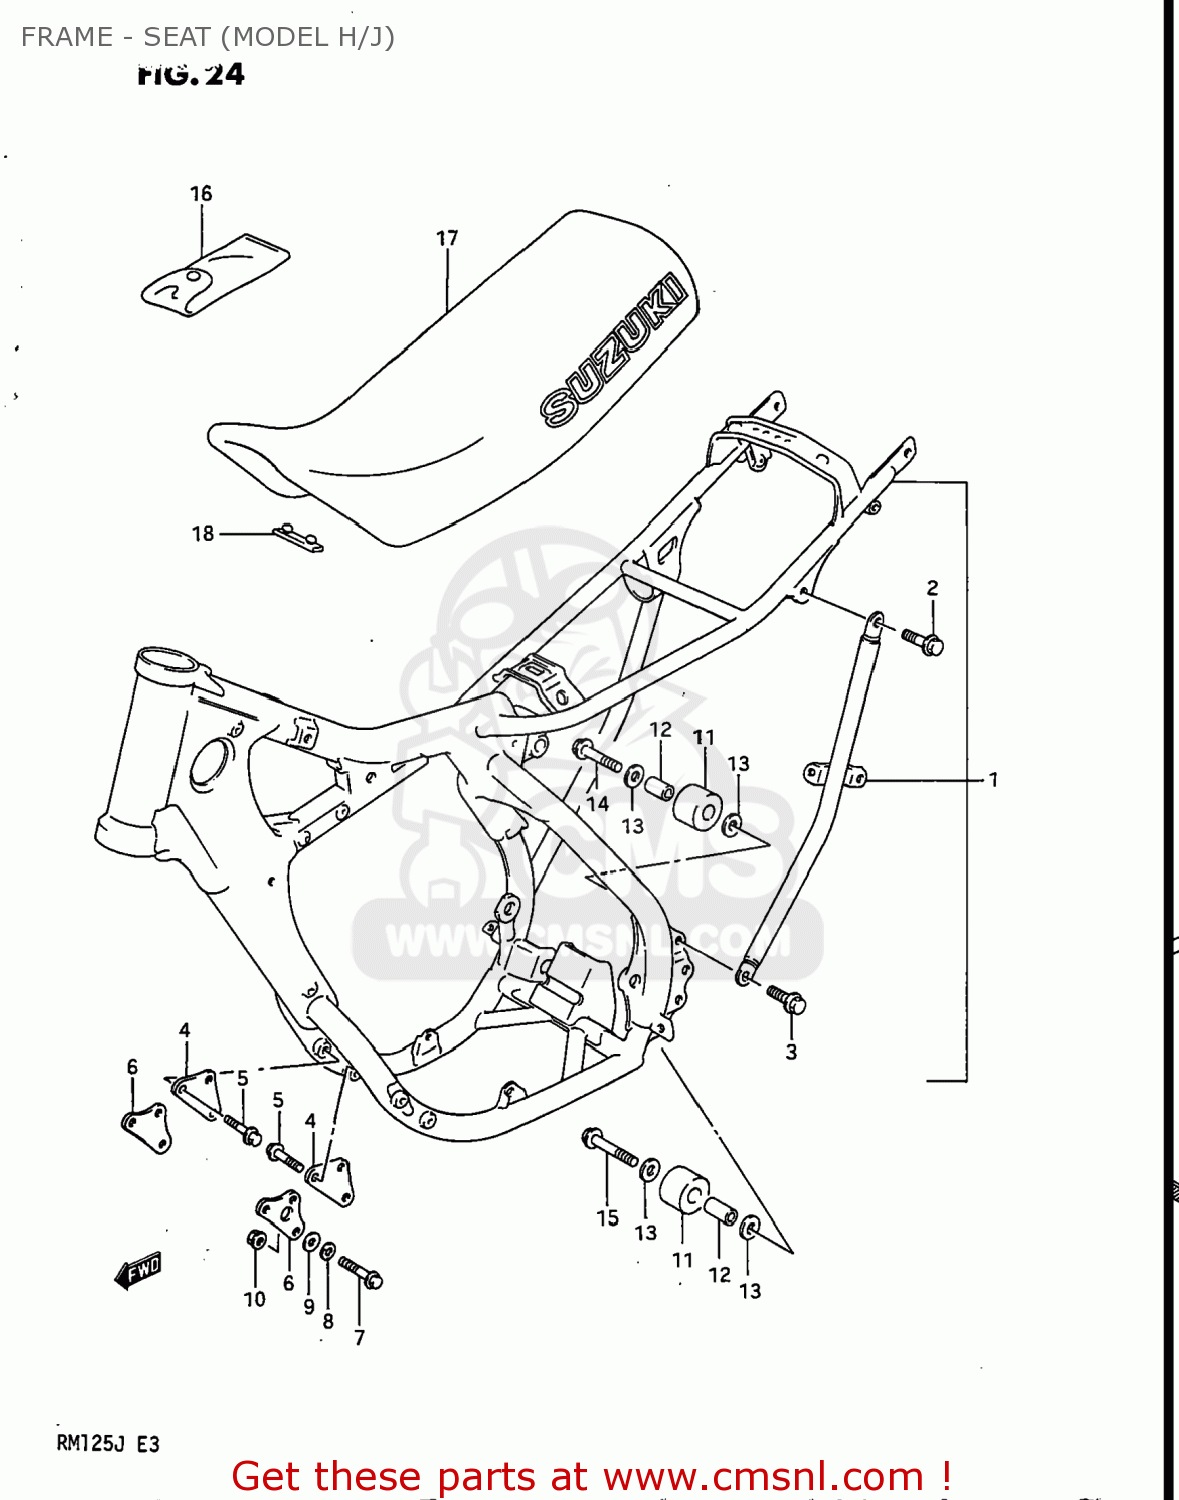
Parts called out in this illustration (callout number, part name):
1	FRAME
2	BOLT
3	BOLT
4	PLATE,ENGINE MOUNTING
5	BOLT(8X36)
6	PLATE,ENGINE MOUNTING,FRONT
7	BOLT 8X55
8	LOCK WASHER
9	WASHER
10	NUT
11	ROLLER,CHAIN CONTROL
12	SPACER (8.6X13.8X28)
13	WASHER
14	BOLT(8X45)
15	BOLT 8X55
16	TOOL SET
17	SEAT ASSEMBLY
18	CUSHION
